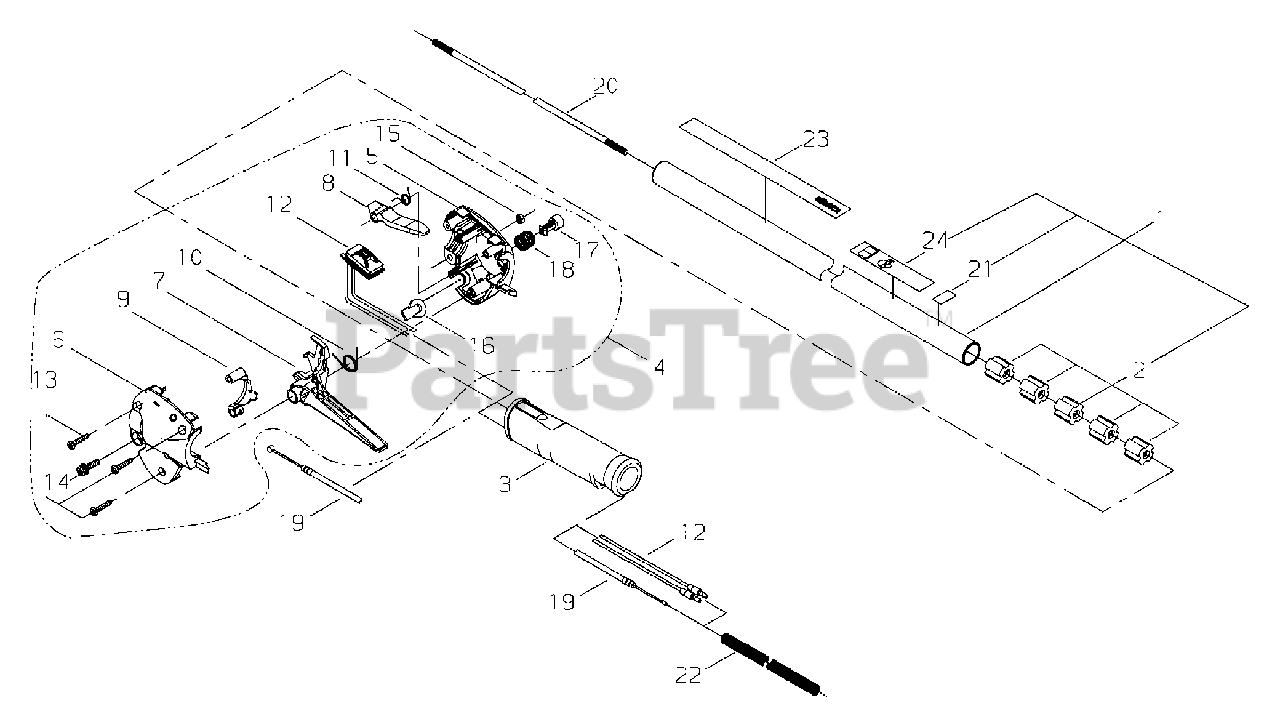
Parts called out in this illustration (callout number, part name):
1	MAIN PIPE ASSY
2	BUSHING
3	GRIP
4	THROTTLE CONTROL ASSY
5	CONTROL HANDLE - RIGHT
6	CONTROL HANDLE - LEFT
7	TRIGGER, THROTTLE
8	LEVER, THROTTLE LOCKOUT
9	LOCKOUT, THROTTLE
10	SPRING, THROTTLE RETURN
11	SPRING, THROTTLE LOCKOUT
12	SWITCH, ON-OFF
13	SCREW, TAPPING M4×20
14	SCREW M5×20
15	NUT M5
16	PLUG
17	BUTTON, THROTTLE LOCK
18	SPRING, COMPRESSION
19	CABLE, THROTTLE
20	MAINSHAFT
21	LABEL, HANDLE
22	TUBE, PLASTIC PROTECTIVE
23	LABEL, SHINDAIWA PROFESSIONAL
24	LABEL, CAUTION (NON-BLADE CAPABLE)
